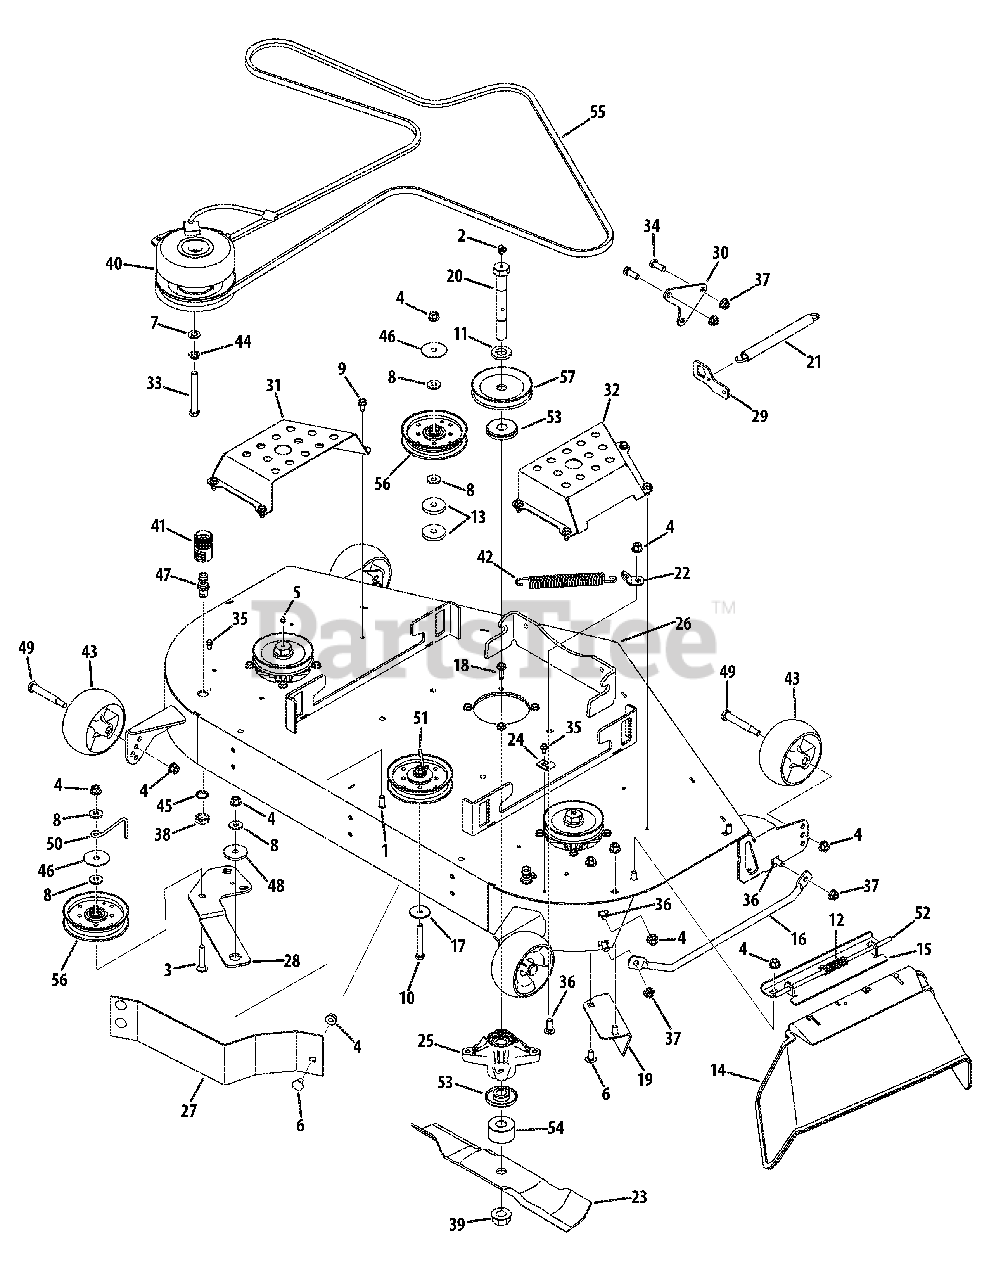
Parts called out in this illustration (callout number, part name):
1	Hex Screw, 3.8-16 x 2.50
2	Grease Fitting, 1.4-28 x .788
3	Carriage Bolt, 3.8-16 x 2.00
4	Counterlock Flange Nut, 3.8-16
5	Straight Grease Fitting, 1.4-28
6	Carriage Bolt, 3.8-16 x .75
7	Washer, .469 x .875 x .105
8	Washer, .406 x 1.00 x .105
9	TT Screw, 5.16-18 x .625
10	Hex Screw, 3.8-16 x 2.75
11	Spacer, .812 x 1.47 x .218
12	Torsion Spring
13	Washer, .438 x 1.75 x .250
14	Fab Deck Deflector Chute
15	Deflector Chute Bracket
16	Fab Deck Chute Finger Guard
17	Washer, .390 x 1.50 x .122
18	Flange Hex TT Screw, 5.16-18 x 1.00
19	Micro Chute Baffle
20	Hex Screw, 3.4-16 x 6.00
21	Hook Ext. Spring, .75 x 7.89 x .14
22	45-Degree Spring Mount Bracket
23	Hi-Lift Blade, 17.0
24	Retainer Hook Bracket
25	Spindle Assembly
26	48" Welded Deck
27	48" Standard Baffle
28	48" Plate Idler
29	Spring Mount Bracket
30	Spring Mount Plate
31	48" LH Belt Cover
32	48" RH Belt Cover
33	Hex Screw, 7.16-20 x 3.50
34	Hex Screw, 3.8-16 x 1.00
35	Hex Washer TT Screw, 1.4-20 x .500
36	Carriage Bolt, 3.8-16 x 1.00
37	Flange Lock Nut, 3.8-16
38	Hex Nut, M16-1.5
39	Flange Lock Nut, 3.4-16
40	Electric PTO Clutch
41	Water Nozzle Adapter
42	Extension Spring, .91 x 7.33
43	Deck Wheel, 5.0
44	Lock Washer, 7.16
45	Lock Washer, 17 x 23.8 x 1.95
46	Flat Washer, .406 x 1.92 x .060
47	Water Deck Nozzle
48	Shoulder Spacer, .884 x .190
49	Shoulder Bolt, 3.8-16 x .496 x 2.50
50	Belt Keeper Rod
51	Belt Keeper Rod
52	Chute Deflector Rod
53	Deck Spindle Spacer
54	Spindle Spacer, .76 x 2.0 x 1.1
55	Hi-Performance Belt
56	Idler Pulley
57	V-Type Pulley
